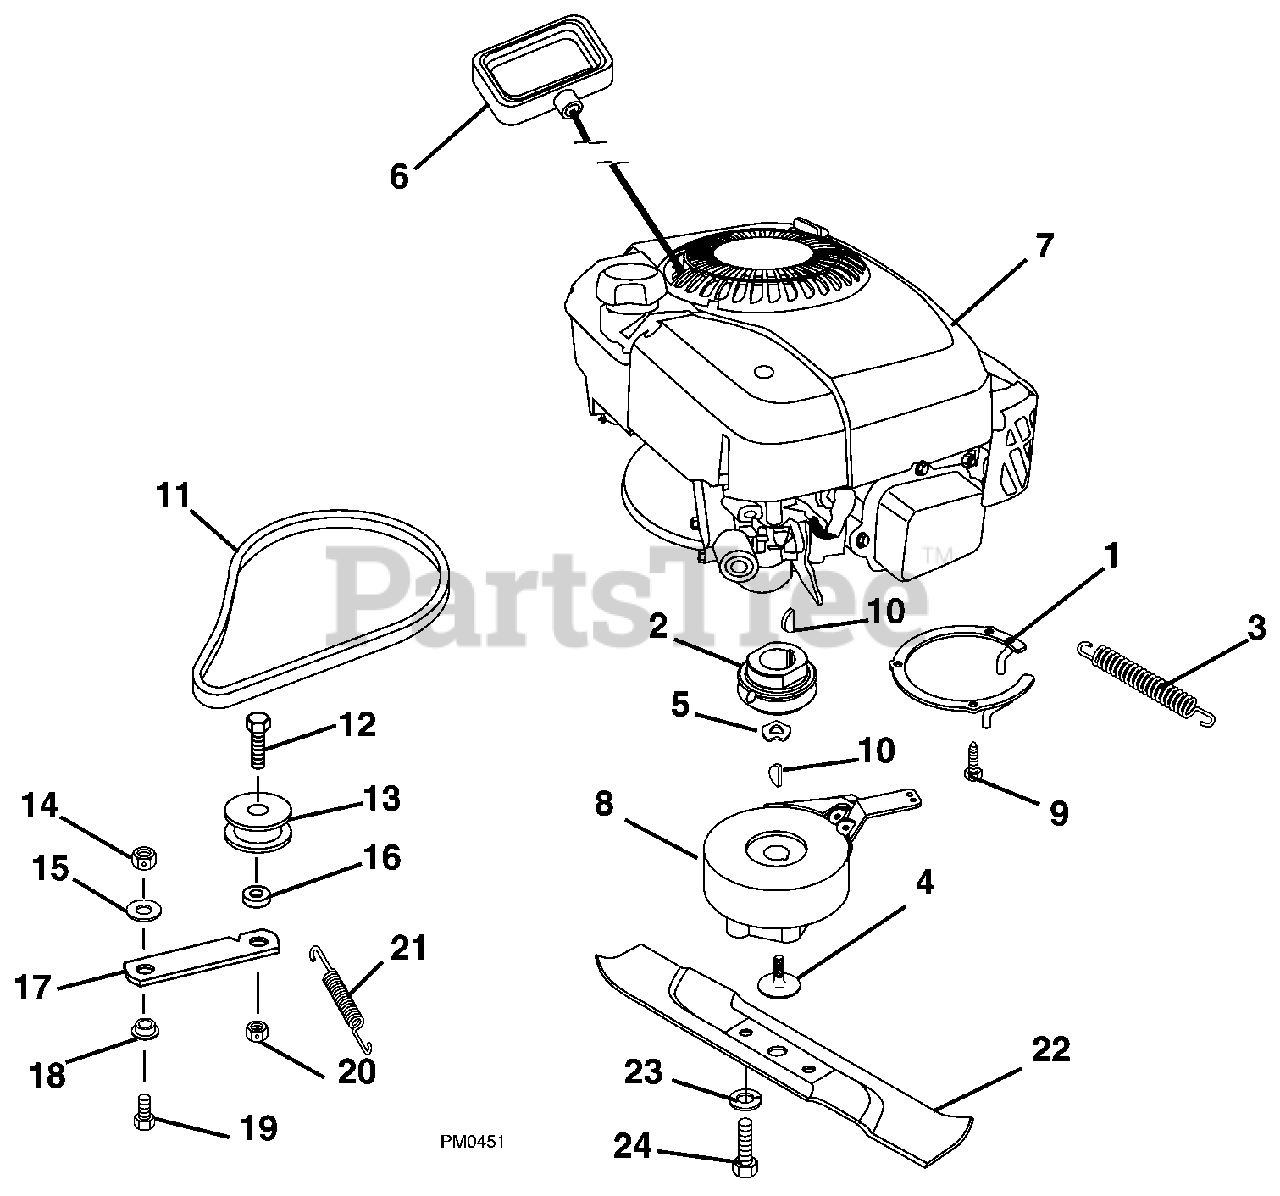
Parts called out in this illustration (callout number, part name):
1	Bracket- Spring Retainer
2	Pulley- Blade Brake/Clutch
3	Spring-Tension .1278 x .735 x 4.71
4	Screw-Socket Head-Special .375-24 x 1.50
5	Washer-Wave .88 x 1.31 x .125
6	Recoil Start Handle
7	Engine, Briggs & Stratton Intek OHV 6.5HP Recoil
8	Blade Brake Clutch
9	Screw-Tapping .38-16 x 1.00 Hex Washer Head
10	Key-Woodruff .156 x .625 x .25
11	V-Belt 3L Section
12	Bolt-Hex .44-14 x 1.50 Grade 5
13	Idler-Flat 1.75 x .47
14	Nut-Locking-Center .31 -18
15	Washer-Flat-Steel .323 x .625 x .062
16	Bushing-Sleeve .469 x .750 x .430
18	Bushing-Flange .325 x .501 x .250 x 1.120
19	Bolt-Hex .31-18 x .75 Grade 5
20	Nut-Locking-Center .44-14
21	Spring, Tension .043 x .44 x 3.31
22	Blade- Blade Brake/Clutch
23	Washer-Locking .44 x .109 Regular
24	Bolt-Hex M10 x 1.5 x 25
